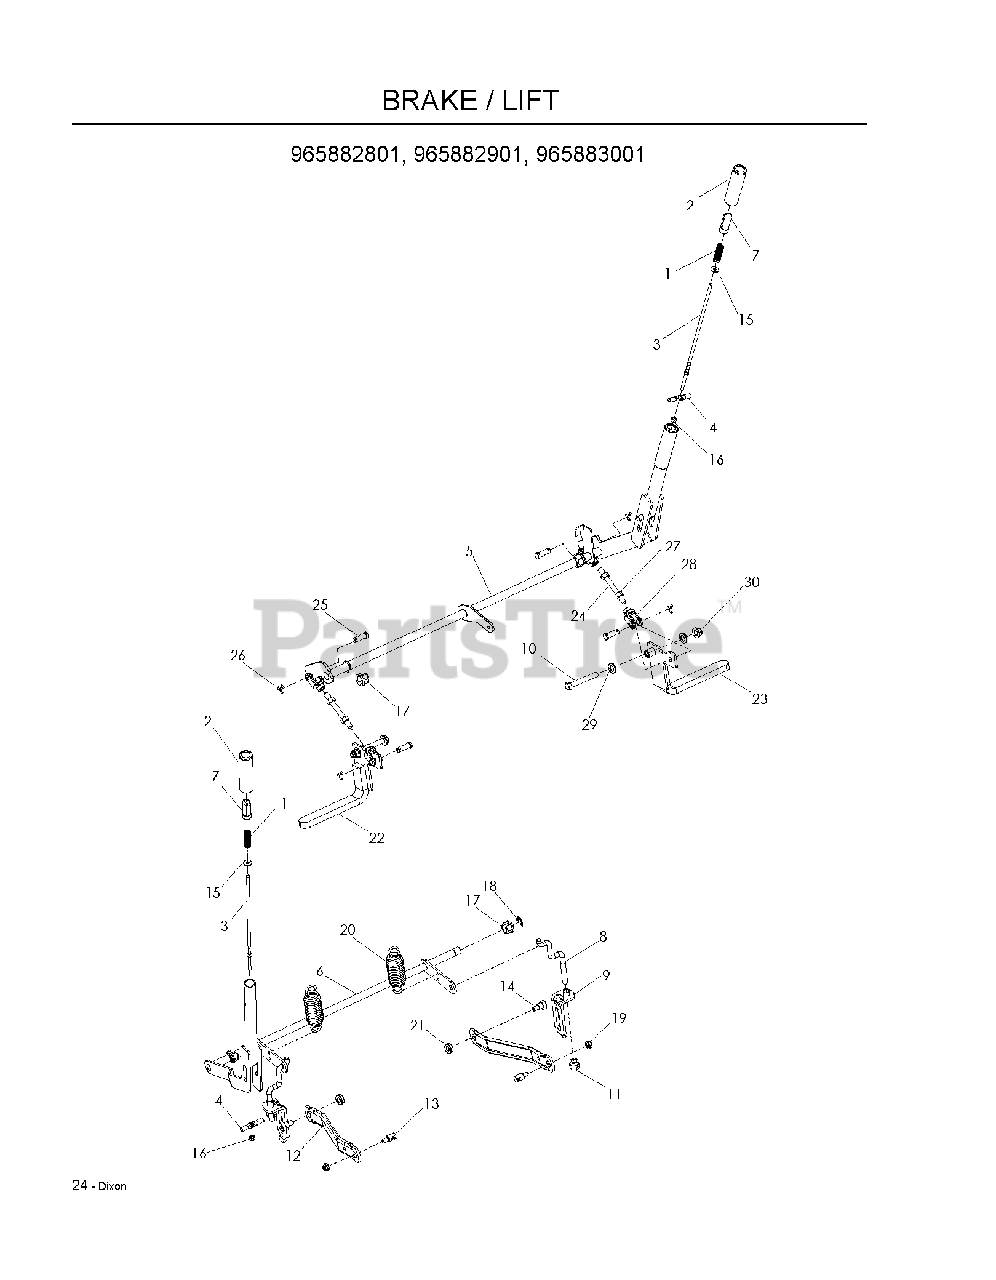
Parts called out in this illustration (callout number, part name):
1	SPRING, COMPRESSION
2	GRIP, HANDLE, BLACK
3	ROD, HANDLE RELEASE
4	ROD, LATCH RELEASE
5	SHAFT.ASSY.BRAKE.WLDMT.BLACK
6	SHAFT, LIFT, BLK
7	BUTTON, PUSH, BLACK (2 2)
8	LINK, REAR SUSPENSION
9	ASSEMBLY, BRKT LINK
10	HCS 3/8C X 3
11	NUT, LIFT LINK 7/16-20
12	ARM.SUSPENSION.MOWER
13	STUD.FASTNER.W/ANTI-ROTATE
14	SB 3/8-16 X 3/8 SKT HD ZD
15	WASHER 1/4 FLAT
16	NUT 1/4-20 NYLOC
17	PLASTIC NUT
18	E-RING 5/8
19	5/16-18 NYLOC FLANGE NUT
22	BRAKE, RT, BLACK
23	BRAKE, LT, BLACK
24	ROD, THRD, 3/8-24
25	CLEVIS PIN 3/8 X 1 1/8
26	COTTER PIN 1/8 X 3/4
27	NUT 3/8F
28	YOKE, 3/8 SHORT
29	WASHER 3/8 SAE FLAT
30	NUT HEX 3/8-16 NYLON, THIN
